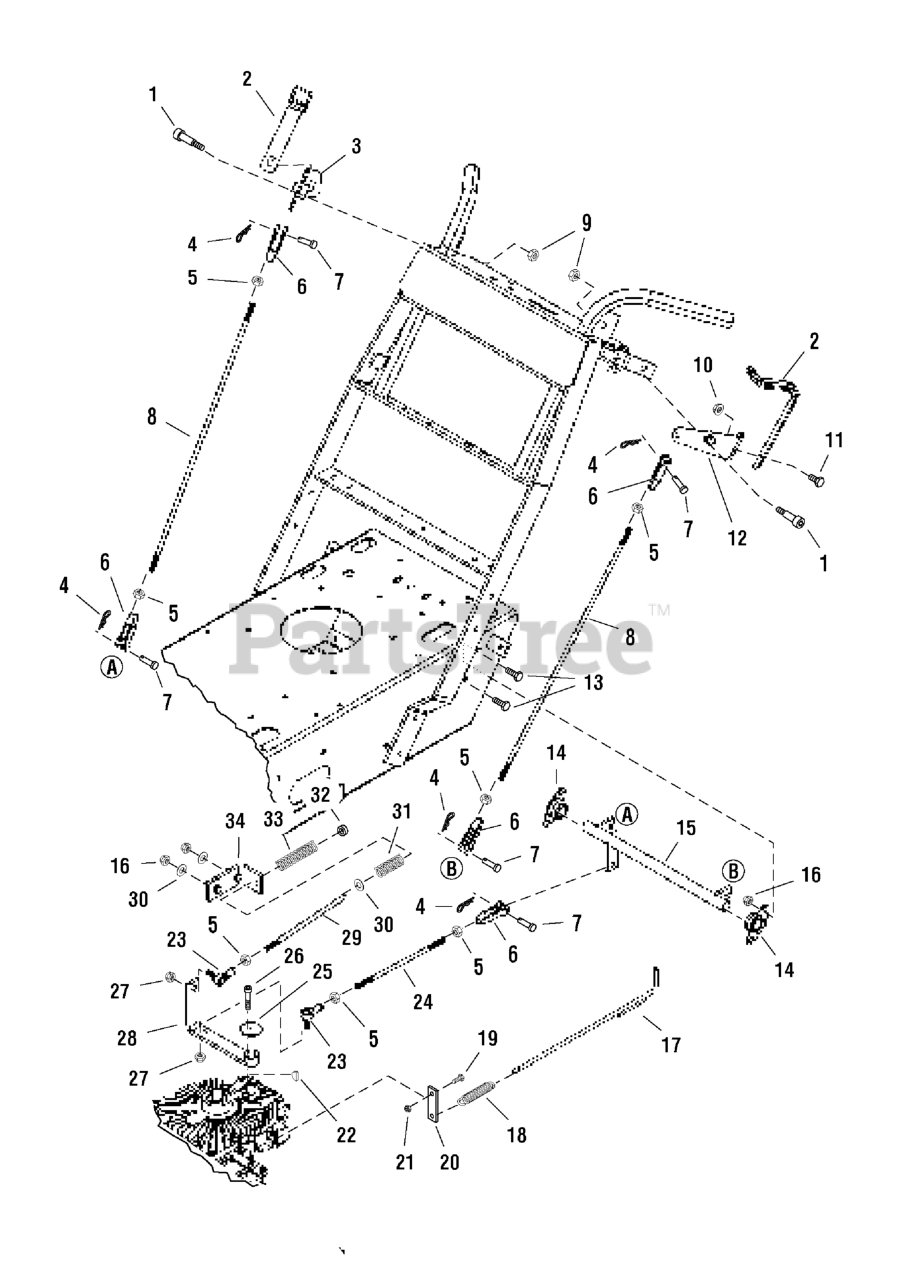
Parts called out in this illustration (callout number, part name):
1	SHOULDER BOLT, 1/2 x 1
2	THUMB CONTROL LEVER, Complete
2	GRIP, FOAM, 1/4 X 1 X 4.1
3	PIVOT CONTROL - RH
4	HAIRPIN CLIP
5	NUT, 5/16-24 Hex
6	CLEVIS, 5/16-24, Plastic
7	CLEVIS PIN, 5/16 x 1
8	ROD, Thumb Control
9	NUT, 3/8-16 Hex Top Lock
10	NUT, 5/16-18 HEX SERRATED FLANGE (SMALL)
11	BOLT, 5/16-18 X 3/4 GD5
12	PIVOT CONTROL - LH
13	BOLT, 5/16-18 X 1 GD5 YZ
14	BEARING, Flange
15	ROD, Transmission Control
16	NUT, 5/16-18 Hex Nylon Lock
17	DUMP VALVE ROD
18	SPRING, Extension
19	BOLT, 1/4-20 X 1" GD5 CZ
20	DUMP VALVE EXTENSION
21	NUT, 1/4-20 HEX NYLON LOCK
22	KEY, #3 Woodruff
23	BALL JOINT 5/16-24 LH FEMALE W/STUD, BR
24	ROD, Control
25	WASHER, .265 x 1.50 x .109
26	BOLT, Allen Head, 1/4-20 x 1-1/2
27	NUT, 5/16-24 HEX NYLON LOCK
28	CONTROL ARM
29	ROD, Neutral
30	WASHER, 5/16" SAE
31	SPRING, Compression
32	COLLAR, 5/16" Set
33	SPRING, Compression
34	NEUTRAL BRACKET
